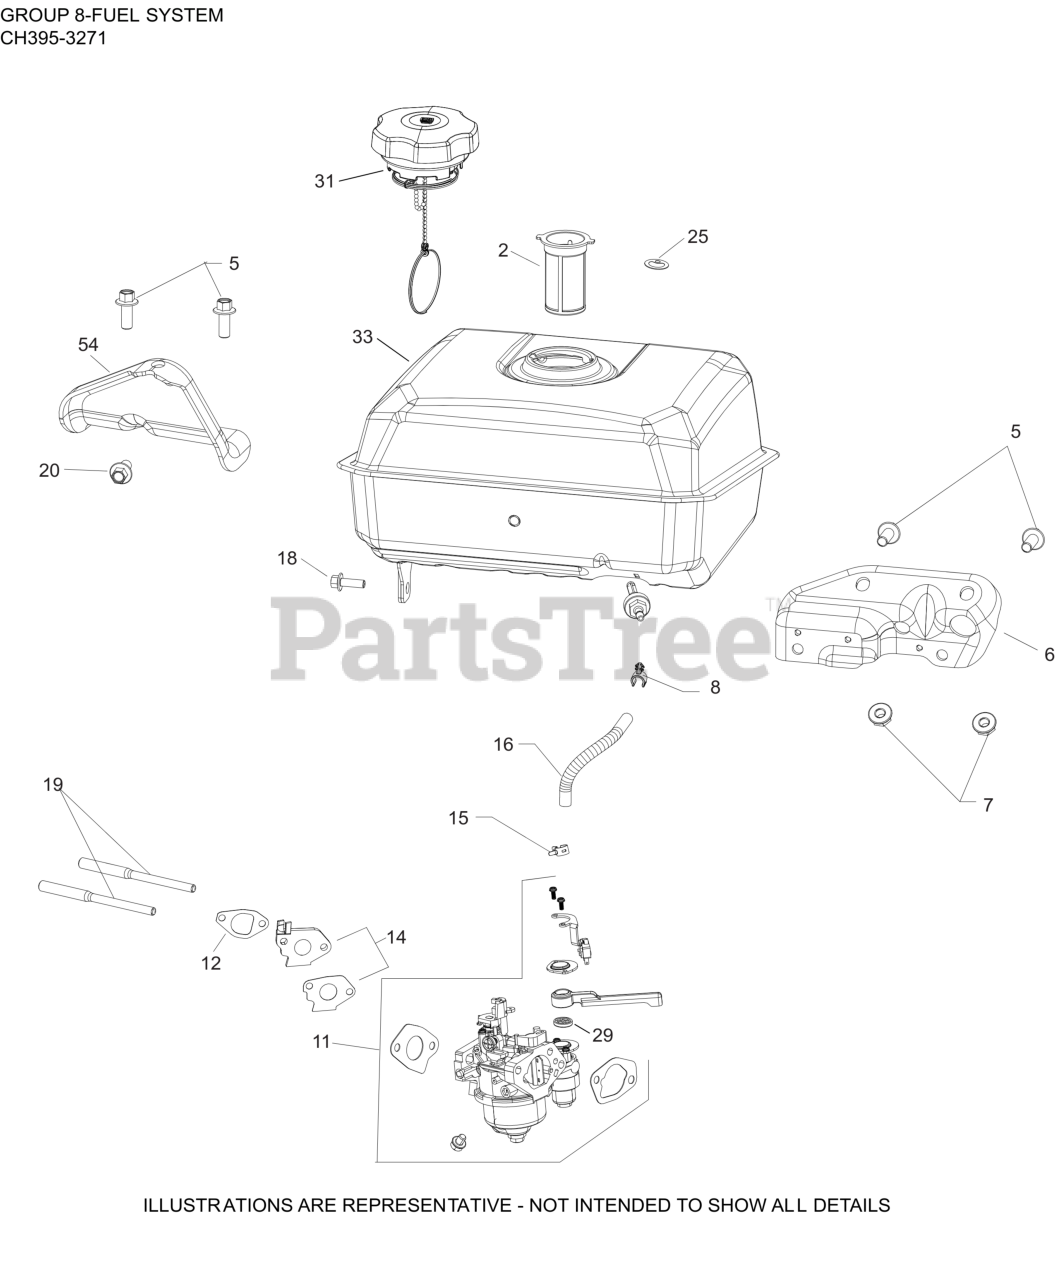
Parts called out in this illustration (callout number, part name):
2	FILTER, FUEL TANK
5	SCREW, M8 X 20
6	BRACKET, FUEL SUPPORT ASSEMBLY
7	NUT, FLG M8X1.25
8	CLIP, FUEL HOSE
11	KIT, CARBURETOR COMPLETE
12	KIT, INTAKE GASKETS
14	INSULATOR AND GASKET KIT
15	CLAMP, FUEL LINE
16	LINE, FUEL (10"-CUT TO LENGTH)
18	SCREW, M6 X18
19	STUD, CARBURETOR
20	SCREW, FLG 8X1.25X16
25	KIT, FUEL SCREEN
29	SEAL, INLET VALVE
31	CAP, FUEL ASSEMBLY
33	TANK, FUEL
54	BRACKET, FUEL SUPPORT
NI	FITTING, FUEL ASSY
NI	KIT, HIGH ALT (4000-8000 FT)
NI	KIT, HIGH ALT (8,000+ FT)
NI	KIT, CARBURETOR REPAIR
